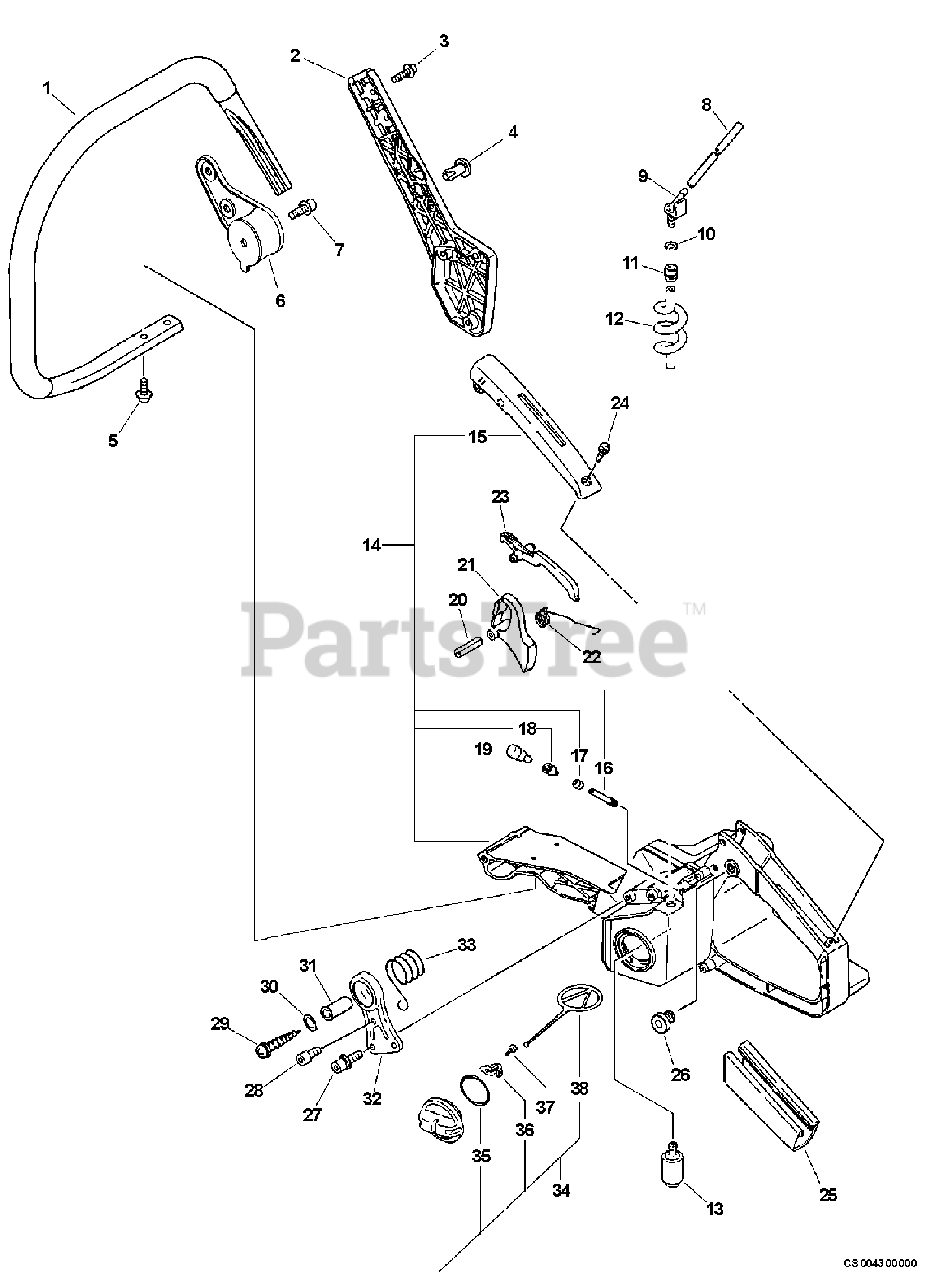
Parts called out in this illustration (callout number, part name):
1	HANDLE - FRONT
2	BRACKET, HANDLE
3	SCREW - 5X20
5	SCREW - 5X14
6	CUSHION
7	SCREW - 5X14
8	PIPE - 3X6X110 -- BLACK
9	CONNECTOR, PIPE
10	CLIP - 6.5
11	GROMMET
12	PIPE - BLACK
13	FILTER, FUEL
14	HANDLE ASSY - REAR
15	COVER, HANDLE
16	PIPE - VENT
17	CLIP - 5.5
18	COVER, VENT
19	VENT, FUEL TANK
20	PIN - SPRING -- 5X25
21	TRIGGER, THROTTLE
22	SPRING, TRIGGER
23	LEVER, TRIGGER LOCKOUT
24	SCREW - 4X14
25	GRIP, HANDLE
27	SCREW - 5X14
28	SCREW - 5X8
29	SCREW - 5X35
30	WASHER - 5
31	COLLAR - 5
32	BRACKET, CUSHION
34	CAP ASSY
35	O-RING - 29
36	RETAINER
37	SCREW - 3X8
38	CONNECTOR, CAP
